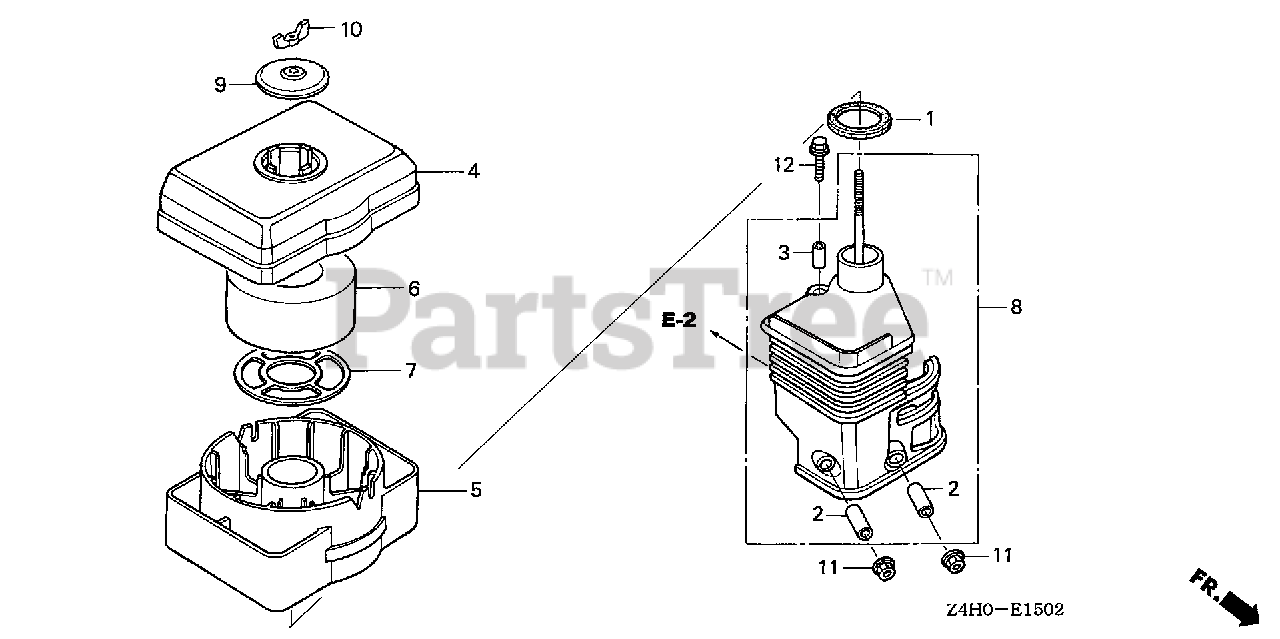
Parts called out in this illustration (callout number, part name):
1	GASKET, ELBOW
2	COLLAR, AIR CLEANER
3	COLLAR B, AIR CLEANER
4	BODY, CLEANER (OIL BATH)
5	PAN, CLEANER OIL (OIL BATH)
6	ELEMENT, AIR CLEANER (OIL BATH)
7	GRID, AIR CLEANER
8	ELBOW, AIR CLEANER
9	CAP, CLEANER
10	WINGNUT, TOOL BOX SETTING
11	NUT, FLANGE (6MM)
12	BOLT, FLANGE (6X20)
